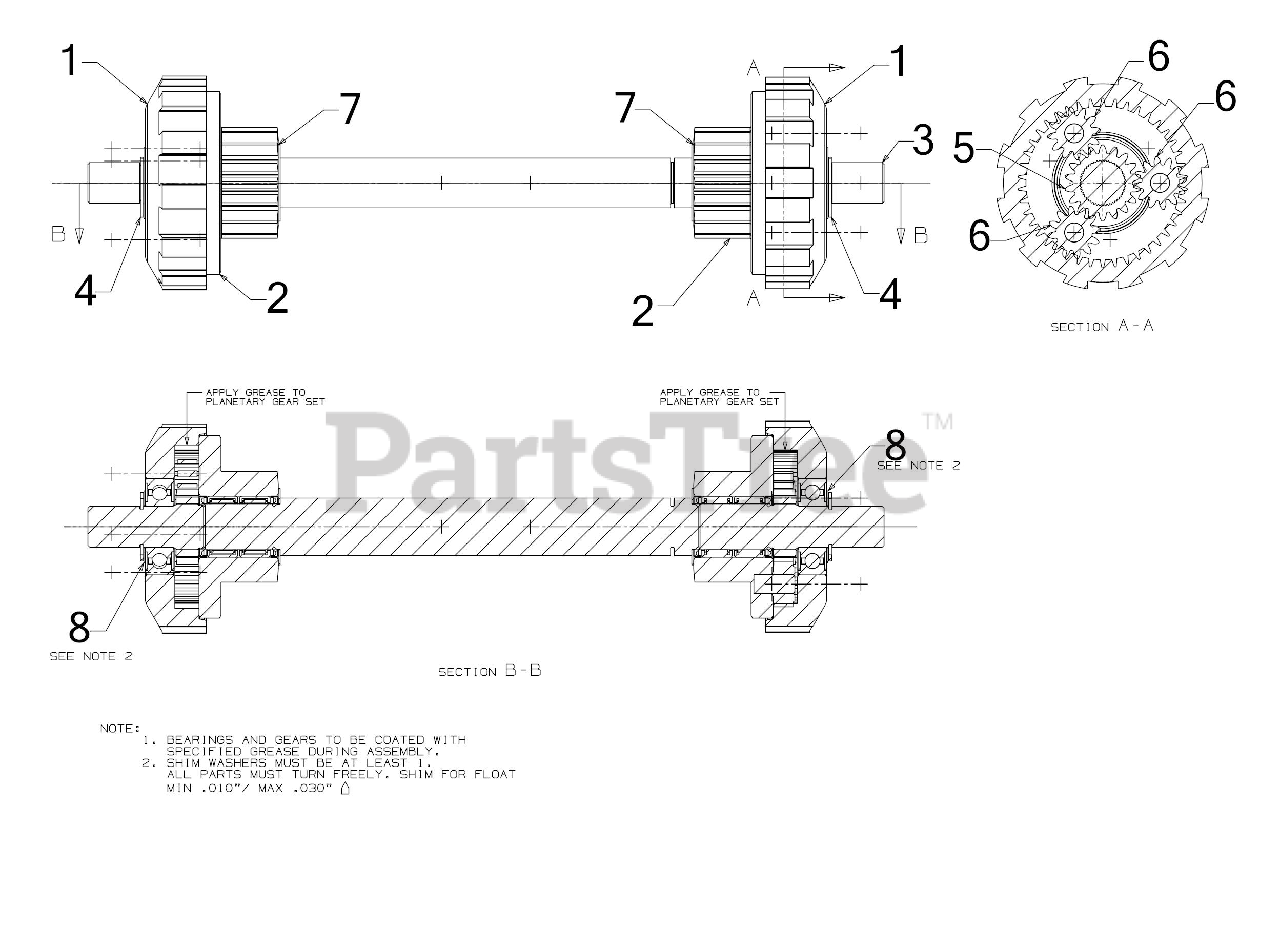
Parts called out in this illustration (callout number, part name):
1	PLANETARY RING GEAR ASSEMBLY
2	PLANETARY CARRIER ASSEMBLY
3	HEX SHAFT
4	E-RING
5	SUN GEAR 18T
7	THRUST WASHER .75X 1.25X .031
8	FLAT WASHER .67X 1.174X .02
